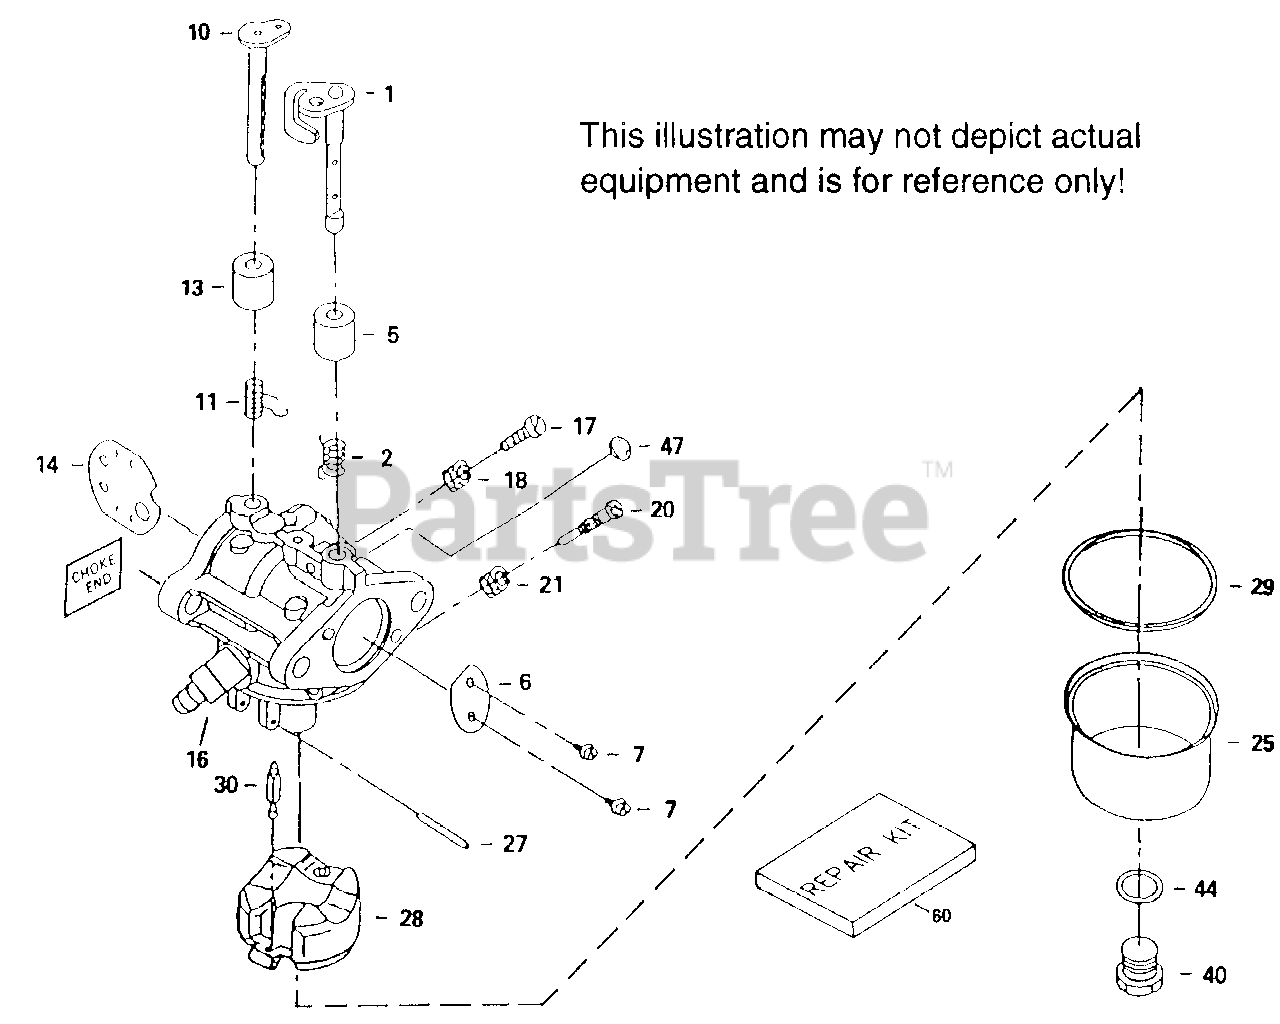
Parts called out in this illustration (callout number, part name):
1	Throttle Shaft & Lever Ass'y.
2	Throttle Return Spring
5	Dust Seal (Throttle)
6	Throttle Shutter
7	Throttle & Choke Shutter Screw
10	Choke Shaft & Lever Ass'y.
11	Choke Return Spring
13	Dust Seal (Choke)
14	Choke Shutter
16	Fuel Fitting
17	Idle Speed Screw
18	Tension Spring
20	* Idle Mixture Screw
21	Idle Tension Spring
25	Float Bowl
27	* Float Shaft
29	* Float Bowl "O" Ring
30	* Inlet Needle
40	Bowl Nut
44	* Bowl Nut Washer
47	* Welch Plug
60	Repair Kit (Incl. items marked PK in notes) Incl. 1 each of 632447,632661, 632663, 632665, 632666,632667
